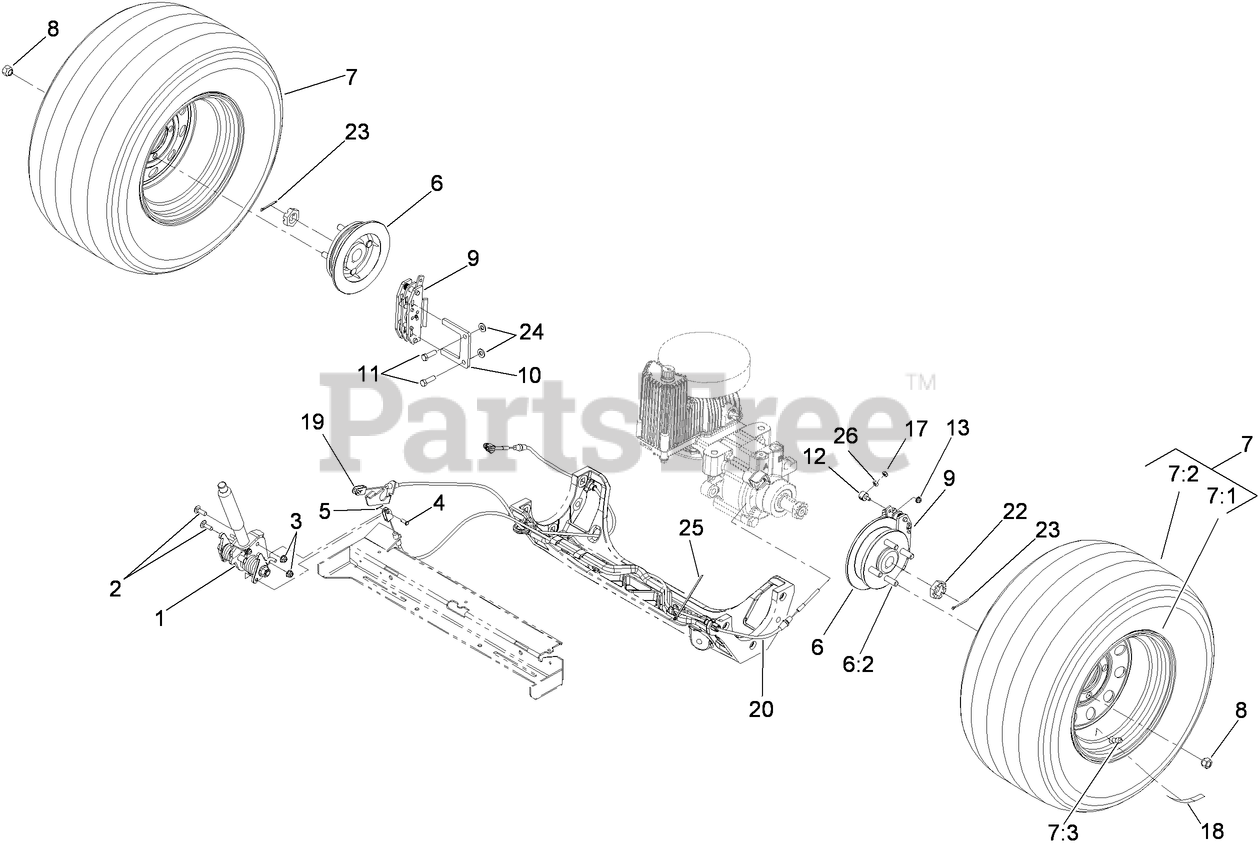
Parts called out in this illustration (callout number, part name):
1	BRAKE HANDLE ASM
2	BOLT-CARR
3	NUT-HF, NI
4	PIN-CLEVIS
5	PIN-COTTER
6	WHEEL HUB AND STUD ASM
6:2	STUD-WHEEL
7	WHEEL AND TIRE ASM
7:3	STEM-VALVE
8	NUT-LUG
9	CALIPER-BRAKE
10	PLATE-MOUNT, BRAKE
11	SCREW-HH
12	SWIVEL
13	NUT-HF
17	NUT-LOCK, NI
18	DECAL-HUB, WHEEL
22	NUT-HH
23	PIN-COTTER
24	WASHER-FLAT
25	TIE-CABLE
26	NUT-HEX
